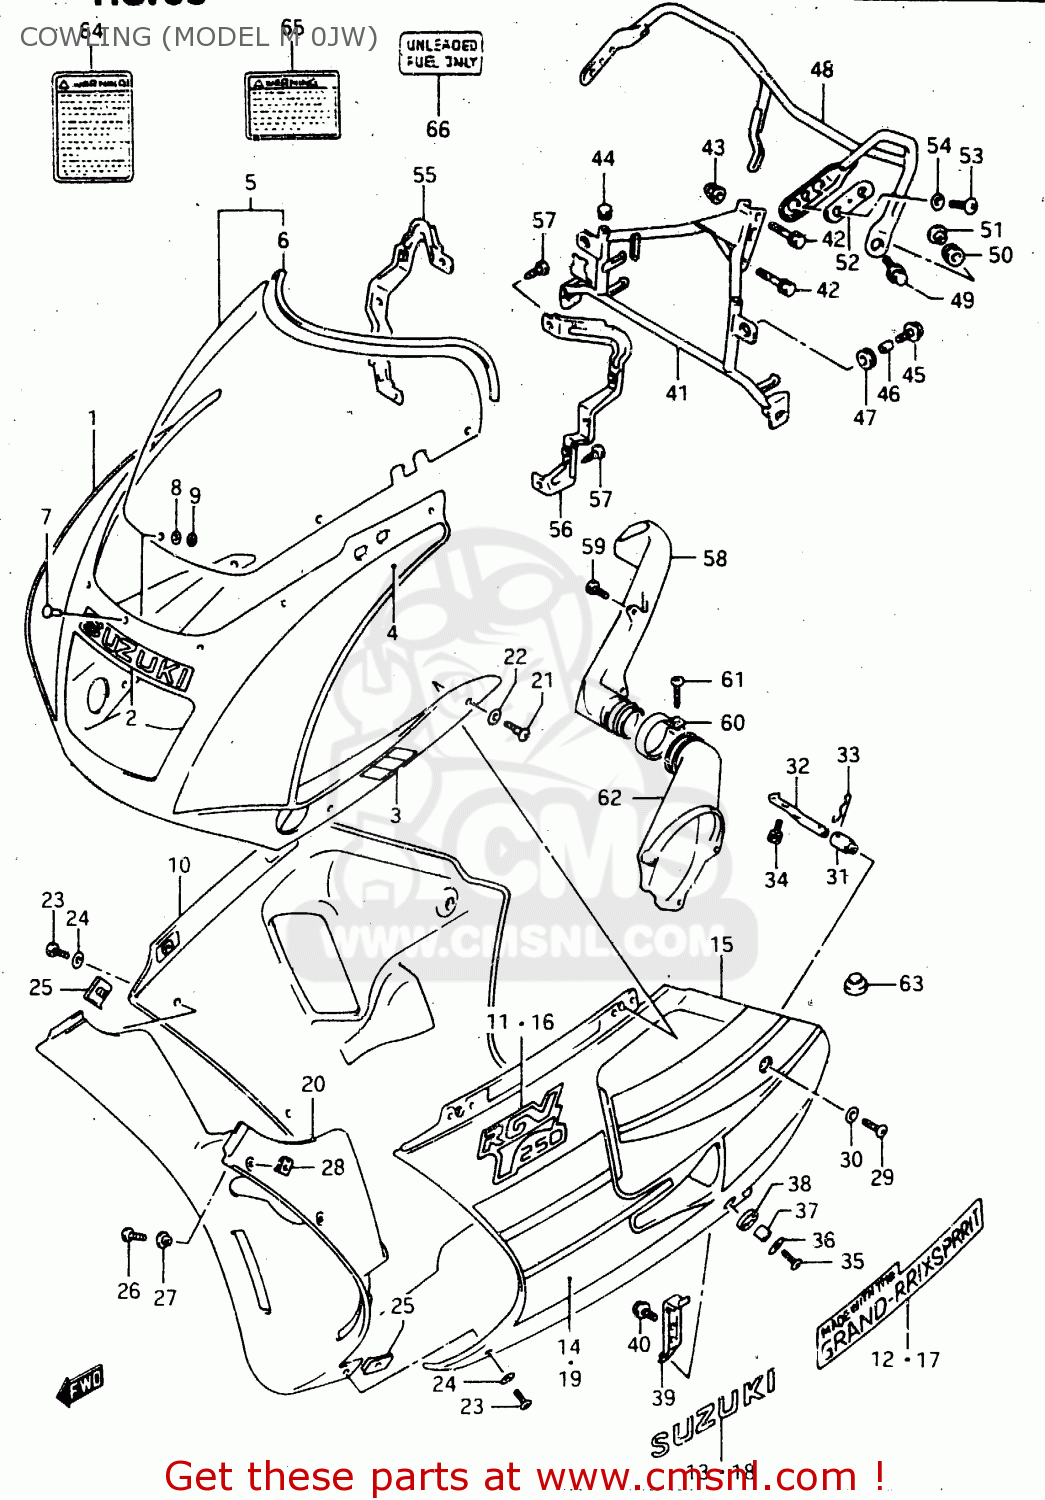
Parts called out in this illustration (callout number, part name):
1	COWLING BODY
2	EMBLEM,SUZUKI
3	TAPE SET,COWL UPR
4	TAPE SET,COWL UPR FR
5	WINDOW SCREEN SET
6	MOLDING
7	PIN,WINDSCREEN
8	CUSHION
9	NUT
10	COWLING ASSY, UNDER RH (WHITE)
11	EMBLEM,UNDER,RGV
12	EMBLEM,COWL UNDER
13	EMBLEM, SUZUKI
14	TAPE SET,COWL UNDER,R
15	COWLING ASSY, UNDER LH (WHITE)
16	EMBLEM,UNDER,RGV
17	EMBLEM,COWL UNDER
18	EMBLEM, SUZUKI
19	TAPESET,COWL U
20	COWLING,UNDER CTR
21	SCREW(5X16)
22	WASHER(7X13X0.6)
23	SCREW(5X16)
24	WASHER(7X13X0.6)
25	NUT,RH & CTR UNDER COWLING
26	SCREW
27	WASHER(5.2X14X1.5)
28	NUT
29	SCREW(6X18)
30	WASHER
31	PLUG,UNDER COWL FTG,CTR
32	PIPE,UNDER COWL FTG CTR
33	PIN,UNDER COWLING FITTING PIPE
34	BOLT
35	SCREW(6X18)
36	WASHER(6.5X18X1)
37	SPACER (6.1X9X10)
38	CUSHION
39	BRACKET, UNDER LH
40	BOLT
41	BRACE,COWL
42	BOLT
43	NUT ,8MM
44	CAP(OD:12)
45	BOLT 6X20
46	SPACER (6.1X9X10)
47	CUSHION
48	BRACE, REAR VIEW MIRROR
49	BOLT 6X20
50	CUSHION
51	WASHER
52	CUSHION,RR VIEW MIRRORR
53	SCREW(6X12)
54	WASHER(6.2X19X1.5)
55	BRACKET,HEADLAMP FIT,R
56	BRACKET,HEADLAMP FIT,L
57	SCREW
58	BODY,AIR DUCT COWL NO.1
59	SCREW, FRONT & REAR
60	CLAMP
61	SCREW 4X25
62	BODY,AIR DUCT COWL NO.2
63	CUSHION
64	LABEL (WARNING SCREEN)
65	LABEL
66	LABEL,FUEL CAUTION
